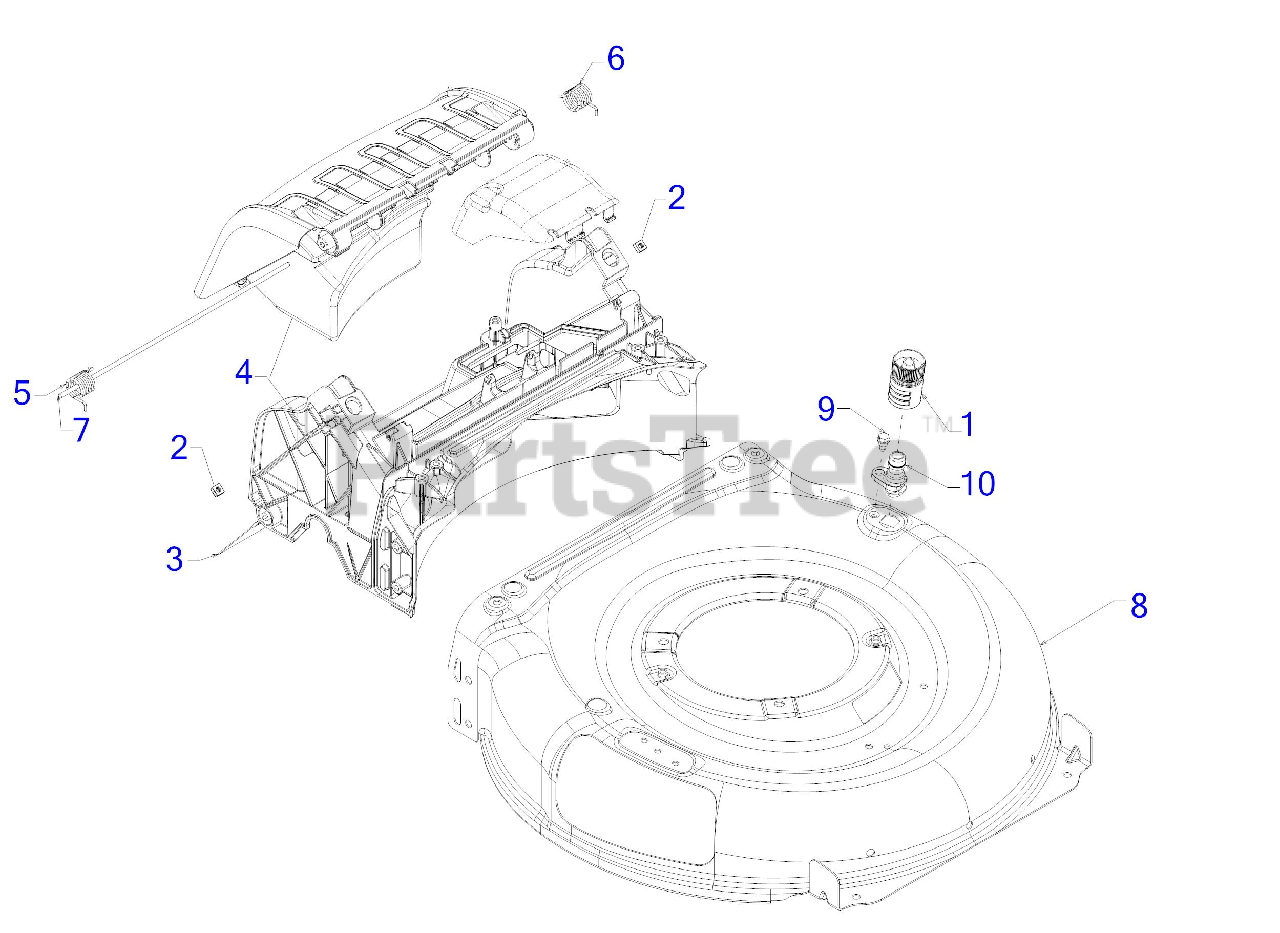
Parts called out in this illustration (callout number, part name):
1	WATER NOZZLE
2	SQUARE NUT 1/4-20
3	TRAILSHIELD
4	REAR BAG BAFFLE ASSEMBLY
5	TORSION SPRING (RH)
6	TORSION SPRING (LH)
7	REAR DOOR PIVOT ROD
8	21" DECK (3N1)
9	SHOULDER SCREW 1/4-20 x .50
10	DECK WASH NOZZLE
